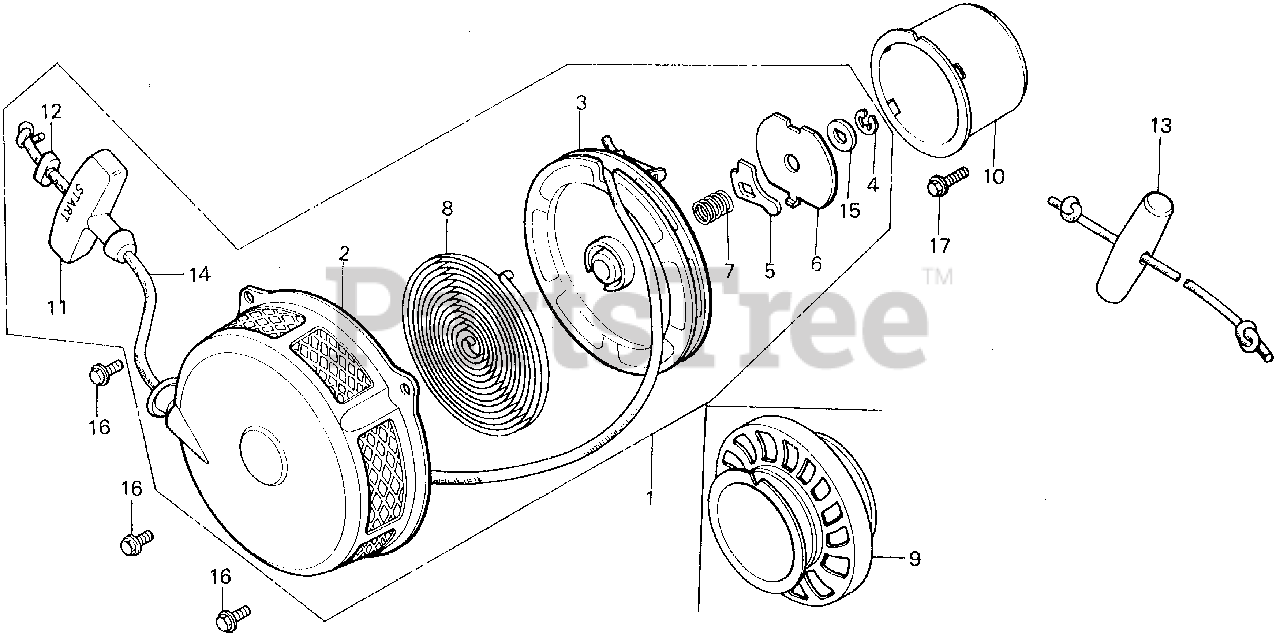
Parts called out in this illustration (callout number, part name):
1	STARTER ASSY., RECOIL *R8* (BRIGHT RED)
1	STARTER ASSY., RECOIL *R8* (BRIGHT RED) (NOT AVAILABLE)
2	CASE, RECOIL STARTER *R8* (BRIGHT RED) (NOT AVAILABLE)
3	PULLEY, RECOIL STARTER
4	E-RING (NOT AVAILABLE)
5	RATCHET, STARTER (NOT AVAILABLE)
6	PLATE, FRICTION (NOT AVAILABLE)
7	SPRING, FRICTION
8	SPRING, RETURN (NOT AVAILABLE)
9	PULLEY, STARTER
10	PULLEY, STARTER
10	PULLEY, STARTER (NOT AVAILABLE)
11	KNOB, STARTER
12	STOPPER, ROPE (NOT AVAILABLE)
13	ROPE, STARTER (#5X55")
14	ROPE, RECOIL STARTER (#5X55")
14	ROPE, STARTER (#5X55")
15	WASHER
15	WASHER (NOT AVAILABLE)
16	BOLT, FLANGE (6X10)
17	BOLT, FLANGE (6X12)
